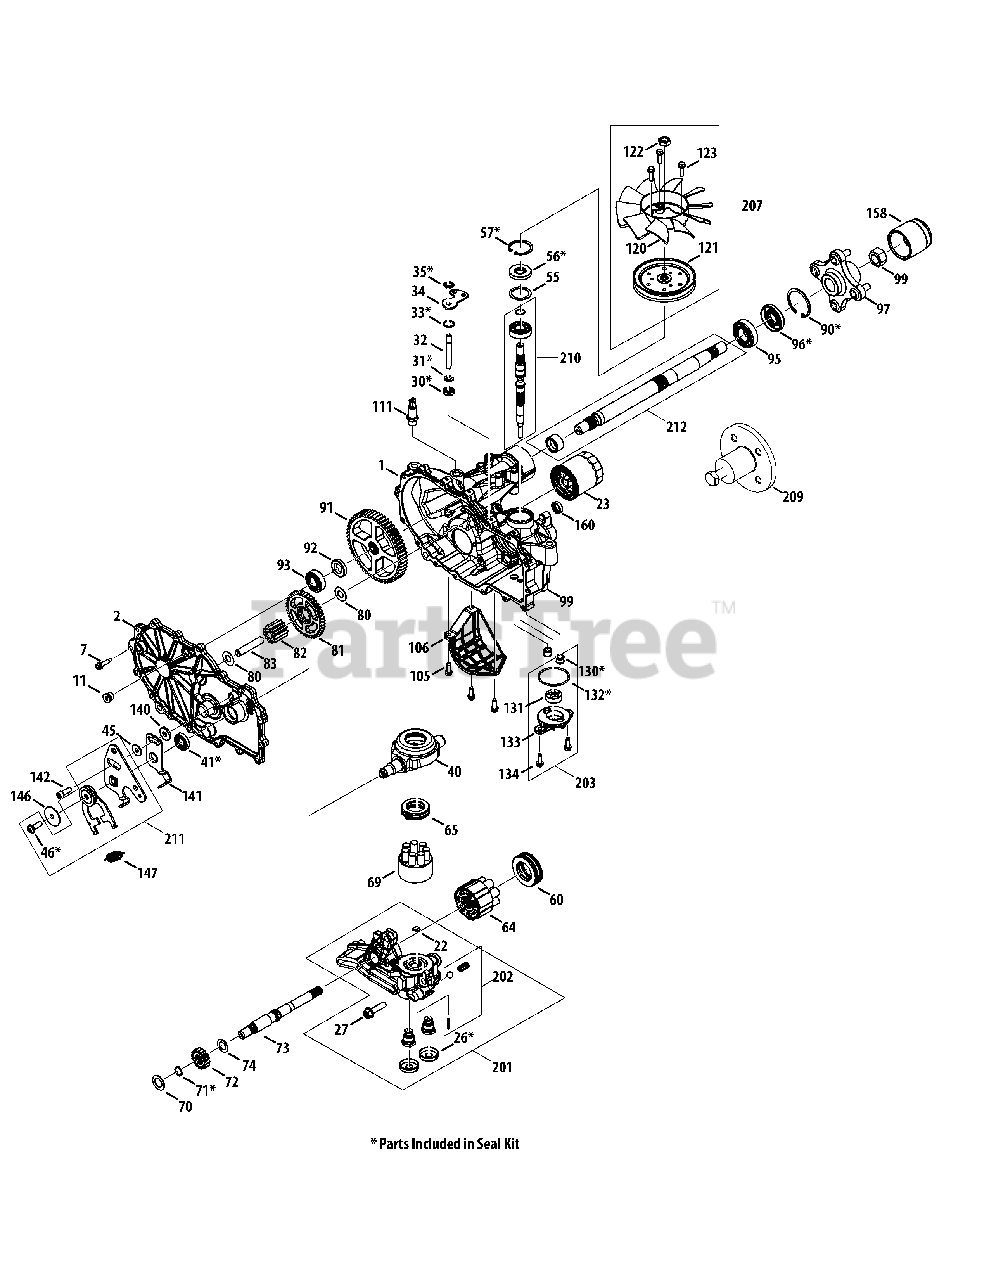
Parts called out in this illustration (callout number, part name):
1	Kit, Housing, Main, LH
2	Kit, Cover, Side, LH
7	Hex Cap Screw, 1/4-20 x 1.125
22	Plate, Bypass
23	Oil Filter
26	Seal, Plug, 1.25 x .25
27	Hex Cap Screw, 3/8-16 x 1.5
30	Seal, Lip .375 x .75 x .25
31	Ring, Ret .375 External
32	Rod, Bypass
33	Ring, Ret .75 Internal
34	Arm, Bypass
35	Ring, Retaining .375 External
40	Trunnion, Swashplate
41	Seal, Lip 12 x 32 x 7
45	Washer, .34 x .88 x .06
46	Hex Cap Screw, 5/16-24 x 1.00
55	Washer, 1.23 x 1.56 x .04
56	Seal, Lip 17 x 40 x 7
57	Ring, Retaining
60	Bearing, Thrust
64	Cylinder Block Assembly
65	Thrust Ball Bearing, 30 x 52 x 13
69	Block 7 Piston Assembly
70	Washer, .63 x 1.0 x .05
71	Retaining Ring, .625
72	Gear, 14t
73	Motor Shaft
74	Washer, .72 x 1.16 x .04
80	Washer, .5 x 1.0 x .03
81	Gear, 45t
82	Gear, 11t
83	Jack Shaft
90	Retaining Ring, 2.06 Internal
91	Gear, 54t
92	Spacer, .75 x 1.32 x .257
93	Ball Bearing, .75 x 40 x 12
95	Ball Bearing, 1.0 x 52 x 15
96	Seal, Lip 25 x 52 x 10
97	Kit, Hub, 4 Bolt
99	Nut, 3/4-16, Hex Lock
105	Hex Cap Screw, 1/4-20 x .75
106	Guard, Filter, LH
111	Fitting, 9/16-18 SAE .5 Barb
120	Fan 7", 10 Blade
121	Disc, Pulley
122	Nut, 1/2-20, Hex Jam
123	Hex Cap Screw, 1/4-20 x .875
130	Connecting Tube
131	Gerotor Assembly
132	O-Ring, -137, .103 x 2.050
133	Charge Pump Cover
134	Hex Cap Screw, 1/4-20 x .75
140	Spacer, .320 x 1.005 x .179
141	Neutral Right Arm
142	Hex Cap Screw, 5/16-24
146	Washer, .343 x 1.5 x .062
147	Extension Spring, .57 x 2"
160	Seal, Lip, .625 x .875 x .25
201	Kit, Center Section, LH
202	Kit, Charge Relief
203	Kit, Charge Pump
207	Kit, Fan & Pulley
209	Hub Puller, 4 Bolt
210	Kit, Input Shaft
211	Kit, RTN, Bidirectional
212	Kit, Shaft, Axle
